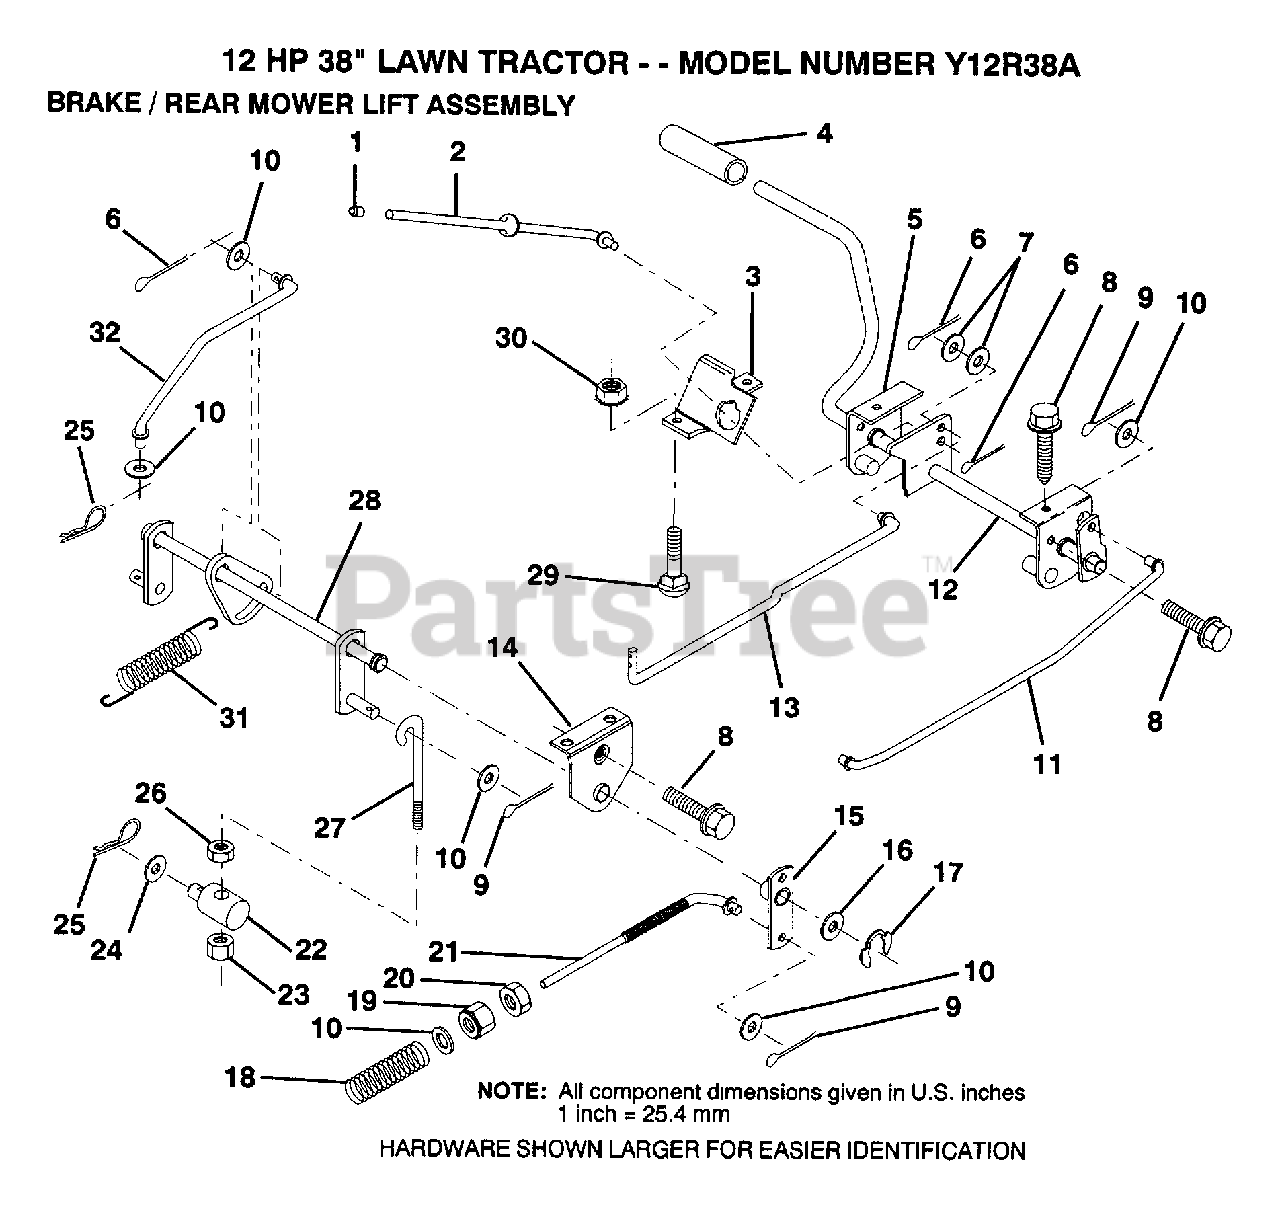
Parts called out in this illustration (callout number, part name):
1	PLUNGER CAP T
2	"ROD,PARK BRAKE"
3	"BRKT,PARK BRAKE"
4	PEDAL COVER T
5	BRK ASM CLUT LH
7	WASHER
8	SCREW LT
9	COTTER PIN
10	WASHER
11	"ROD,FRT BRAKE"
12	ASM CLUTCH/BRK PD
13	"ROD,CLUTCH"
14	"BRKT,LIFT SHAFT"
15	BRAKE PIVOT ARM
16	WASHER T
17	KLIP RING
18	SPRING ROD LT
19	NUT
24	WASHER
25	SPRING.RETAINER
26	LOCKNUT
27	THREADED LINK
28	ASM REAR MOW LIFT
31	COUNTER SPRING
32	LINK LIFT LEVER
